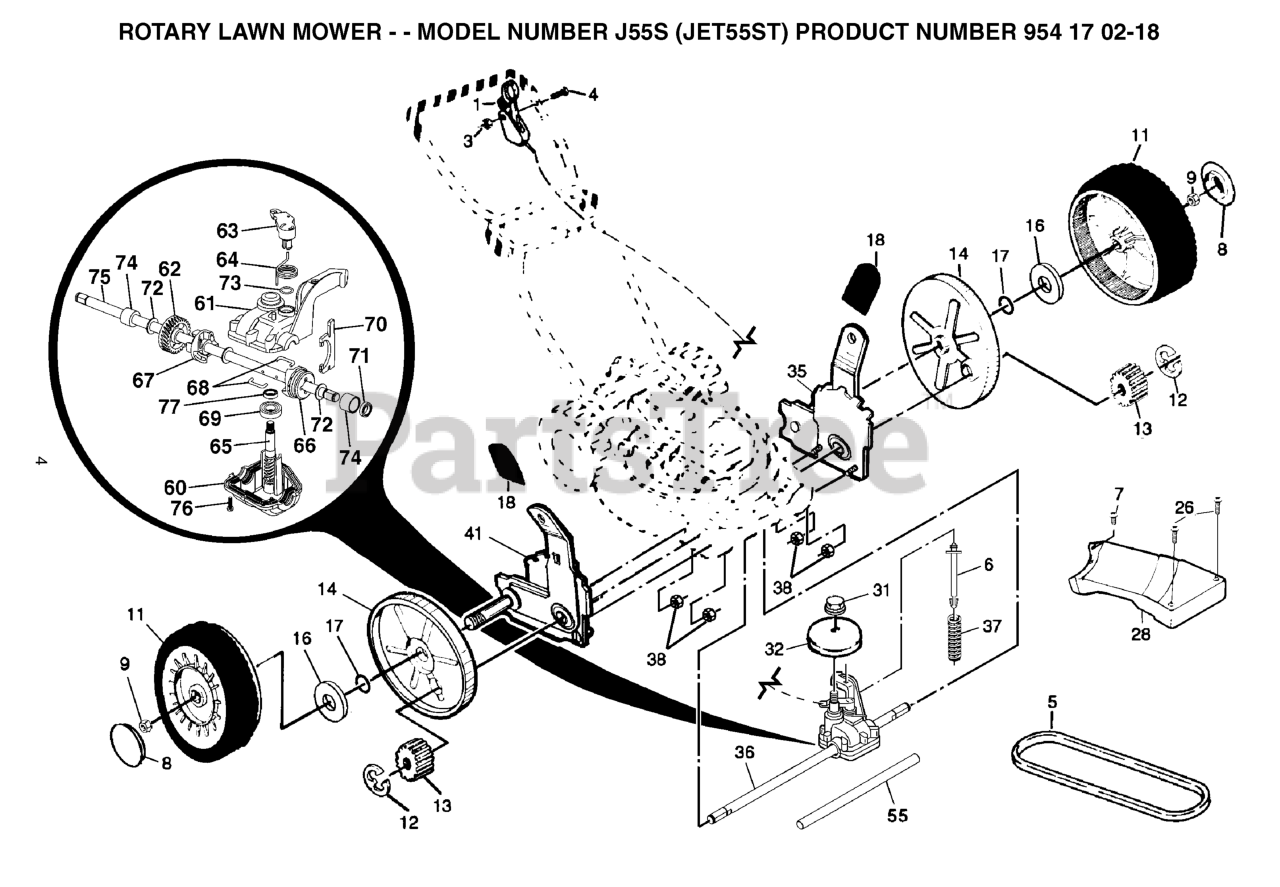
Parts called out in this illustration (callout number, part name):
1	PUSH BUTTON
2	SPRING PUSH BUTTON
3	PUSH BUTTON FRONT
4	SPRING PUSH BUTTON
5	BATTERY BOX
6	SCREW ST3X8
9	SCREW ST4X16
11	COVER BOTTOM
